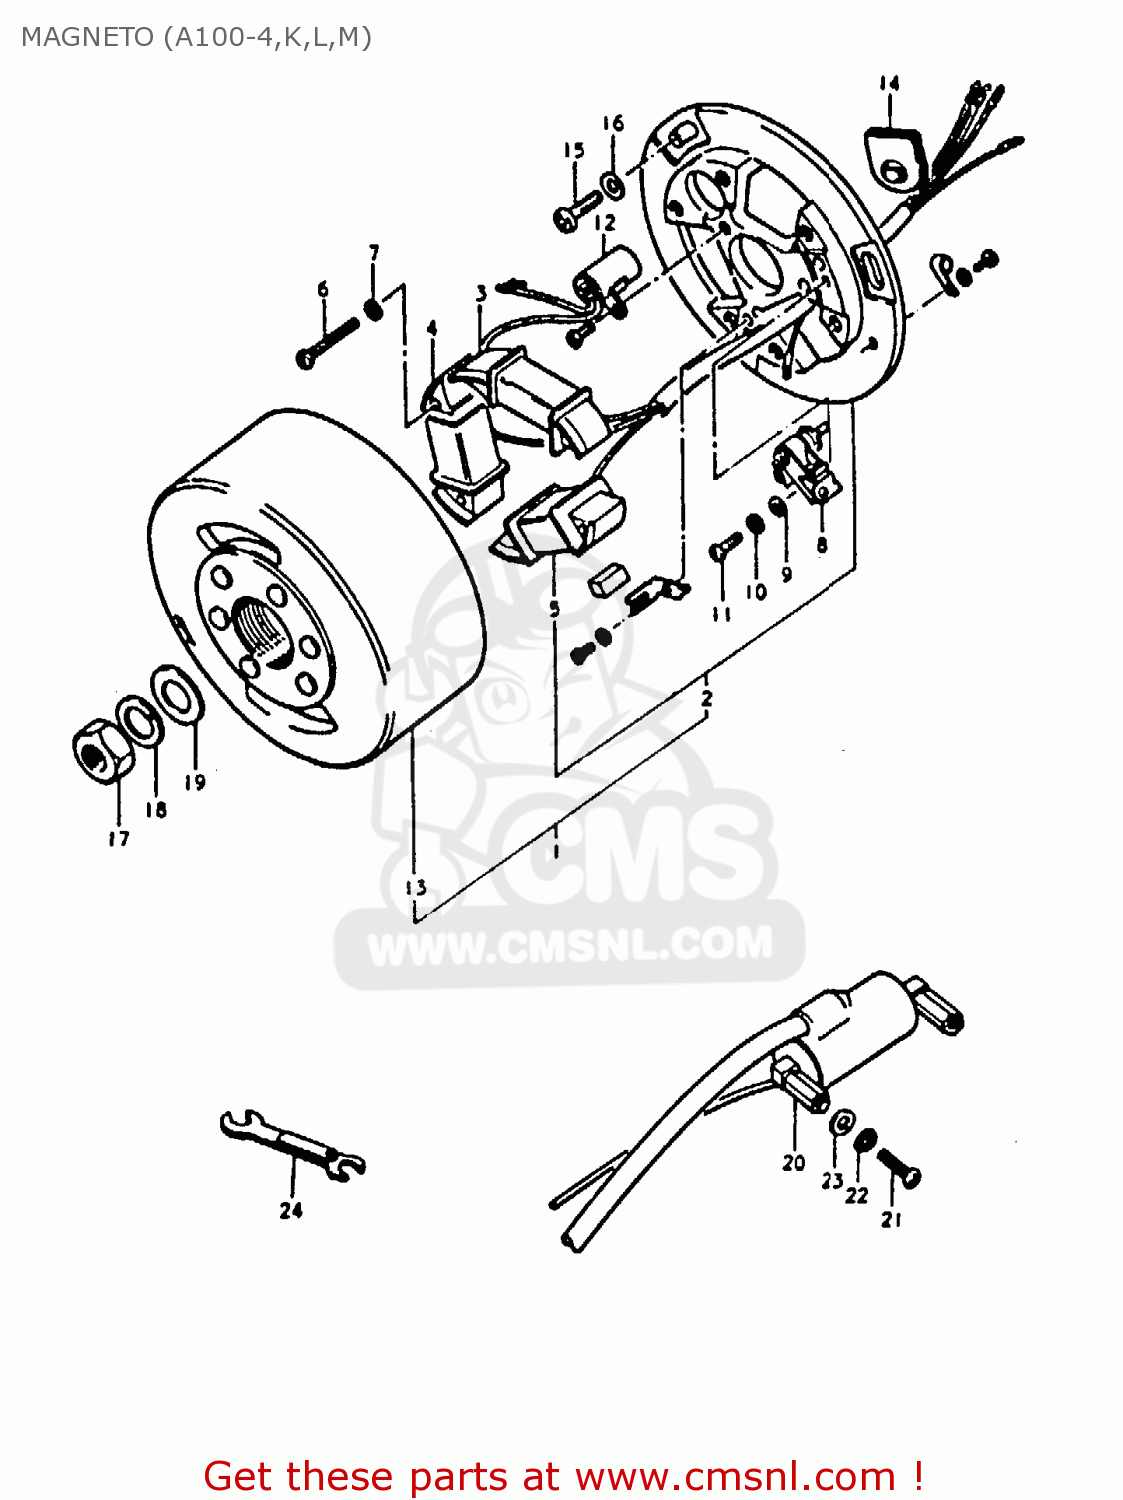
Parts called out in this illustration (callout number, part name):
1	MAGNETO ASSEMBLY
2	STATOR ASSEMBLY
3	COIL,LIGHTING
4	COIL,LIGHTING
5	COIL,PRIMARY
6	SCREW
7	LOCK WASHER
8	POINT ASSEMBLY,CONTACT
9	WASHER
10	LOCK WASHER
11	.SCREW
12	CONDENSER
13	ROTOR ASSEMBLY
14	GROMMET
15	SCREW
16	WASHER
17	NUT (10MM)
18	WASHER
19	LOCK WASHER
20	COIL ASSEMBLY,IGNITION
21	SCREW
22	LOCK WASHER
23	WASHER
